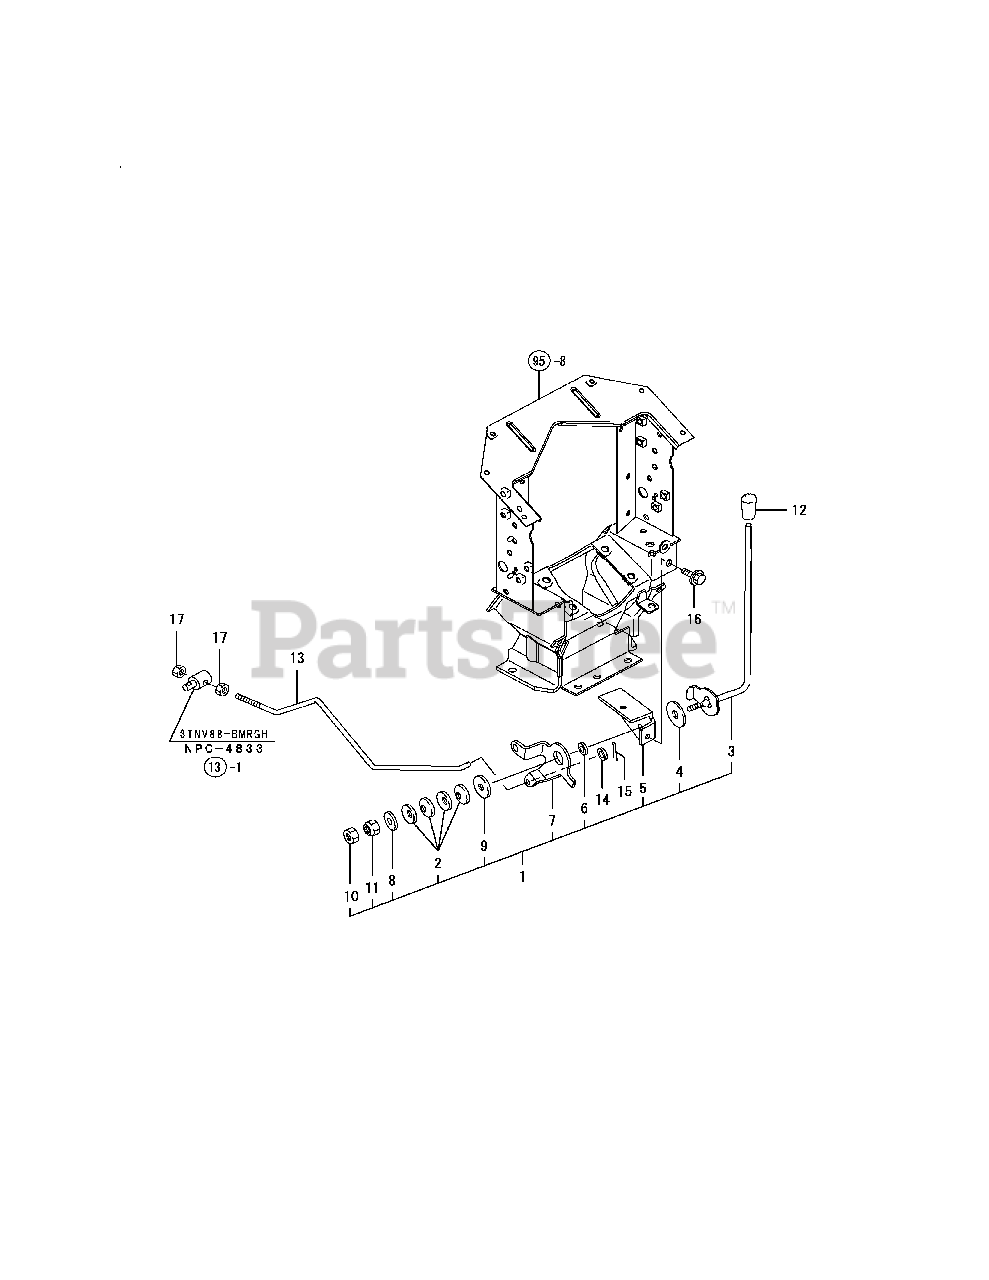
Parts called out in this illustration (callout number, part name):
1	LEVER KIT, ACCELERATOR
2	WASHER 10, CONICAL
3	LEVER, CONTROL
4	PLATE, FRICTION
5	BRACKET, LEVER
7	LEVER, ACCELERATOR
10	LOCK NUT M10 PLATED
12	KNOB, THROTTLE LEVER
13	ROD, ACCELERATOR
14	WASHER 8, POLISHED
15	COTTER PIN 2.5X30
16	BOLT M 8X 16 PLATED
